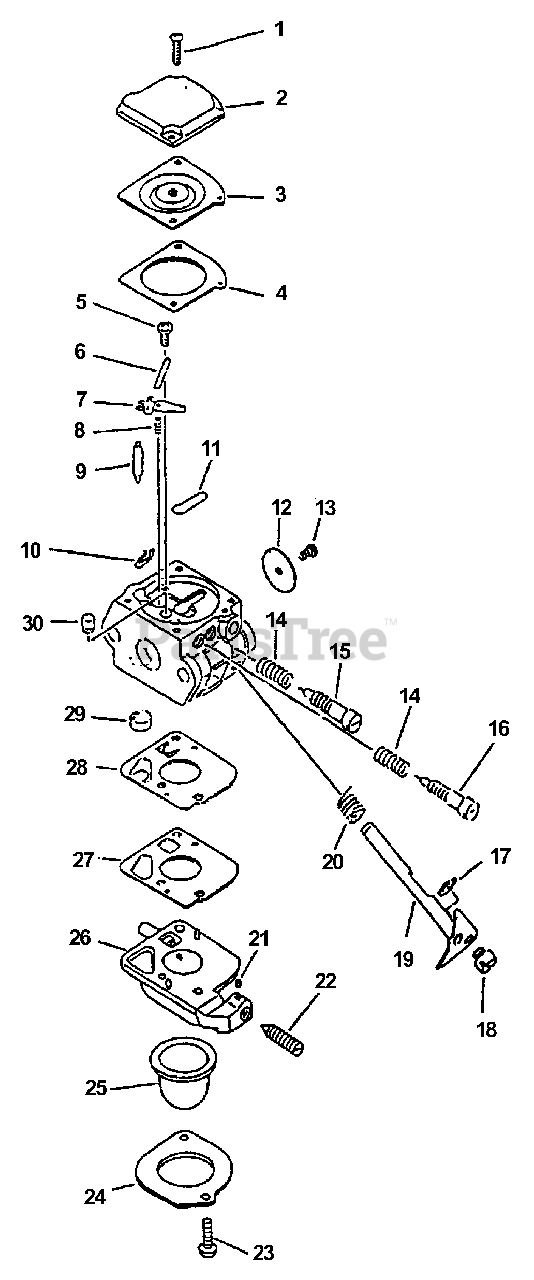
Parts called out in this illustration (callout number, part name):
2	COVER, METERING
3	DIAPHRAGM, METERING
4	GASKET, METERING
5	SCREW, METERING LEVER PIN
6	PIN, METERING LEVER
7	LEVER, METERING
8	SPRING, METERING LEVER
9	VALVE, INLET NEEDLE
10	RING, RETAINING
11	PLUG, WELCH
12	VALVE, THROTTLE
15	NEEDLE - LOW SPEED
16	NEEDLE - MIXTURE
17	RING, RETAINING
19	SHAFT, THROTTLE
20	SPRING, RETURN
21	PIECE, FRICTION
22	SCREW, IDLE ADJUST
24	RETAINER, PURGE BULB
25	BULB, PURGE
26	BASE, PURGE
27	GASKET, PURGE
28	DIAPHRAGM, PURGE
29	STRAINER
30	NOZZLE, CHECK VALVE
